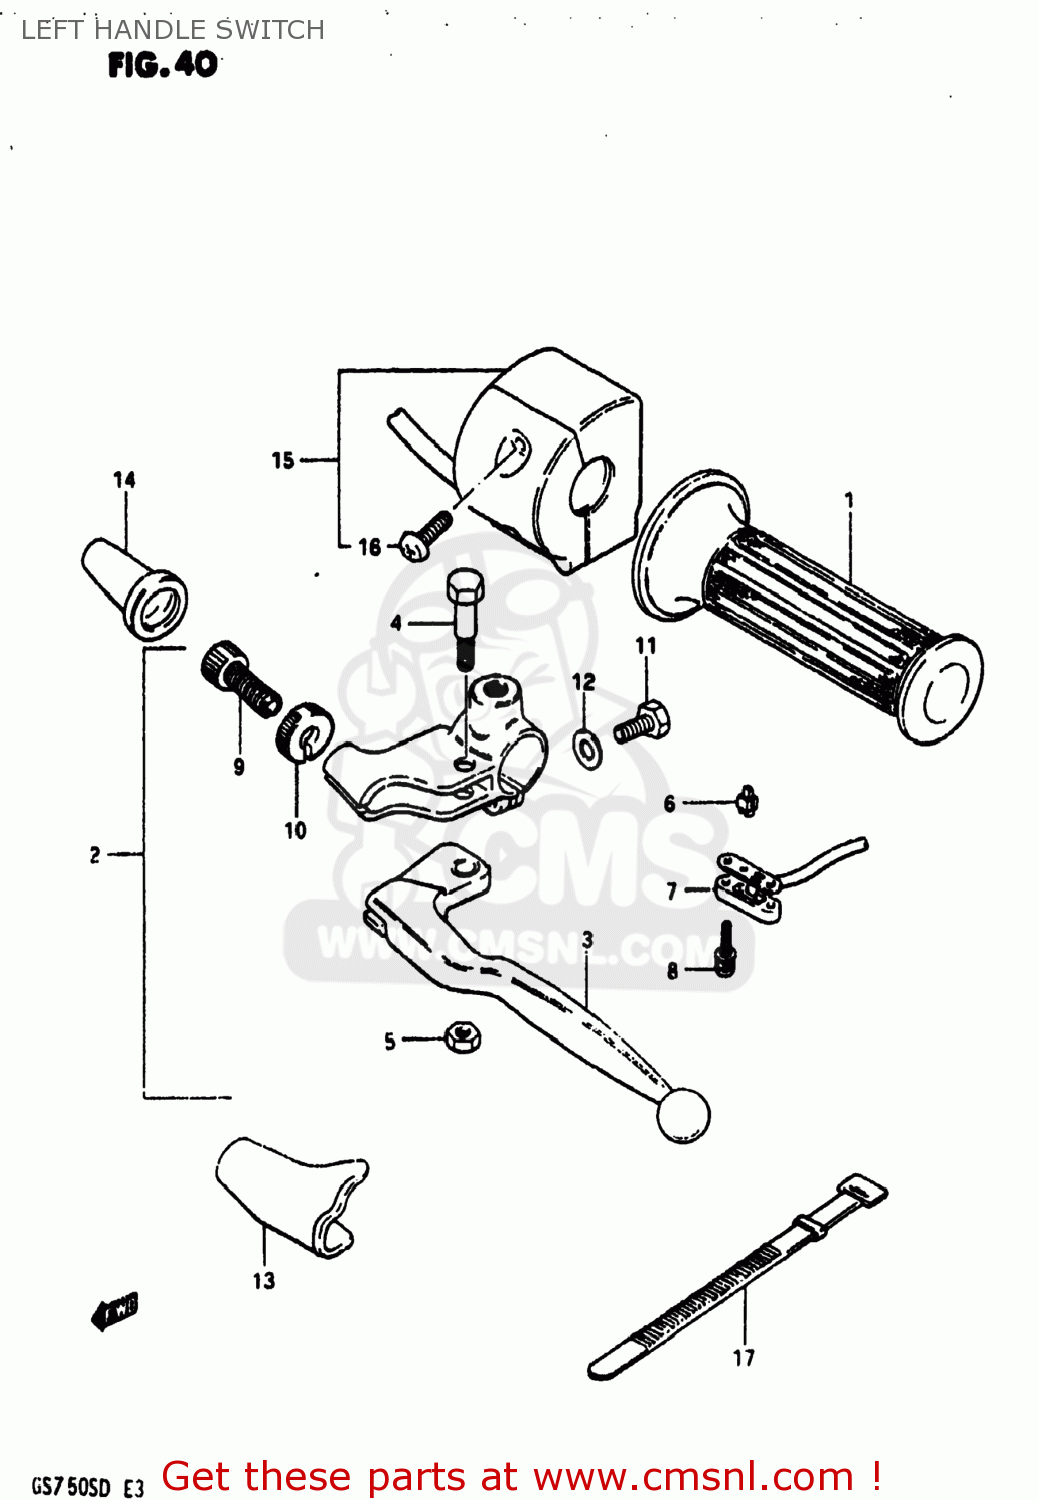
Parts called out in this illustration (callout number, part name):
1	GRIP,L
2	LEVER ASSEMBLY
3	LEVER,CLUTCH
4	BOLT,LEVER
5	NUT 6MM
6	CONTACT,SWITCH
7	COVER,FR BK TERMINAL BASE
8	SCREW
9	ADJUSTER,CABLE
10	NUT,CABLE ADJUSTER
11	BOLT,CLUTCH LEVER HOLDER
12	SPACER
13	COVER,CLUTCH LEVER
14	BOOT,CLUTCH CABLE
15	SWITCH ASSEMBLY,HANDLE,LEFT
16	SCREW
17	CLAMP(L:120)
18	BUTTON,STARTER
19	SPRING,STARTER BUTTON
20	CONTACT,STARTER BUTTON
